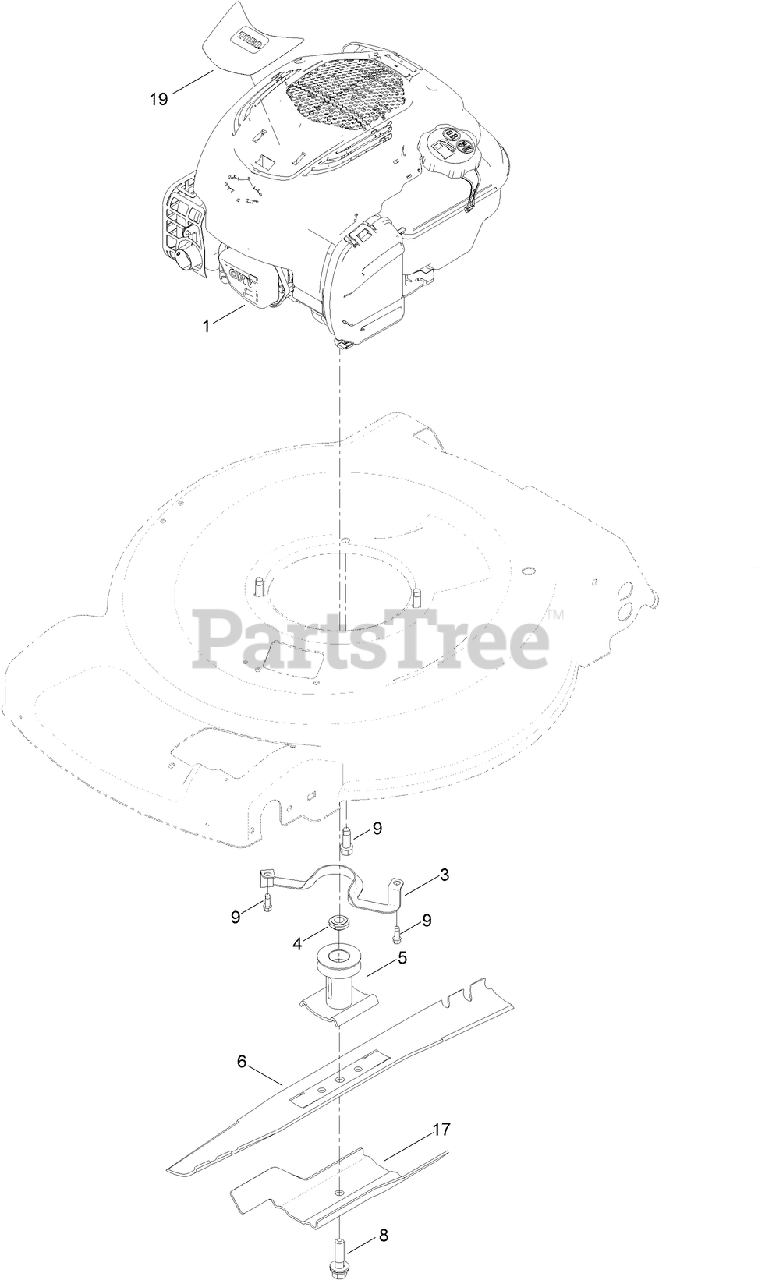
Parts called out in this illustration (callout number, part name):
3	GUIDE-BELT
4	SPACER-DRIVER
5	DRIVER-BLADE
8	BOLT-BLADE
9	SCREW-TAPTITE
17	ACCELERATOR-BLADE
19	DECAL-SHROUD
